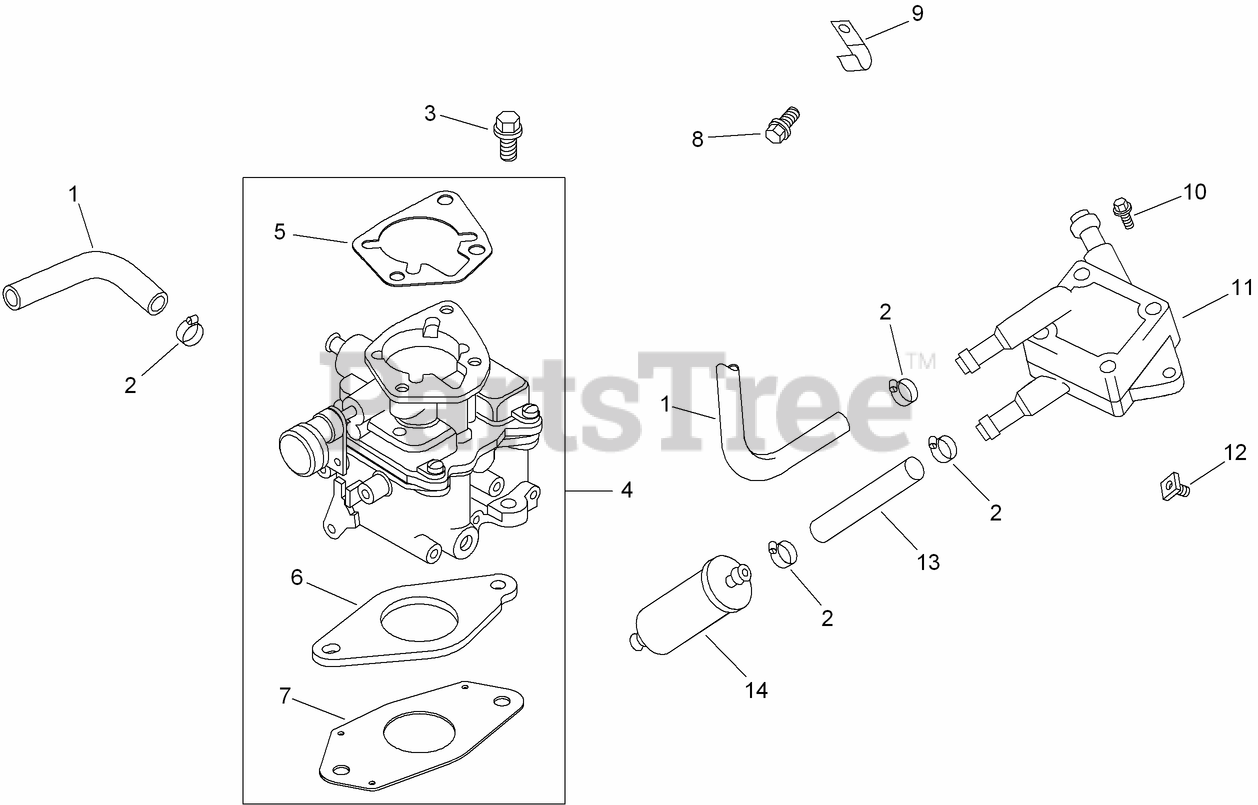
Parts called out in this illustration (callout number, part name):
1	LINE-FUEL (24.0 CUT TO LENGTH)
2	CLAMP-HOSE, SPRING (1/2)
3	SCREW-FLANGE (M6X1.0X30)
4	Carburetor Kit W/GASKETS (INCLUDES 5-7)
5	GASKET-BASE, AIR CLEANER
6	Gasket-Carburetor
7	GASKET-CARBURETOR
8	SCREW-FLANGED, THREAD FORMING (M6X1.0X11)
9	CLIP-CABLE
10	SCREW-TAP (M6X1.7X18)
11	PUMP-FUEL
12	NUT-PLASTIC (BLACK)
13	Line-Fuel, Flexible (15.5)
14	Filter-Fuel
